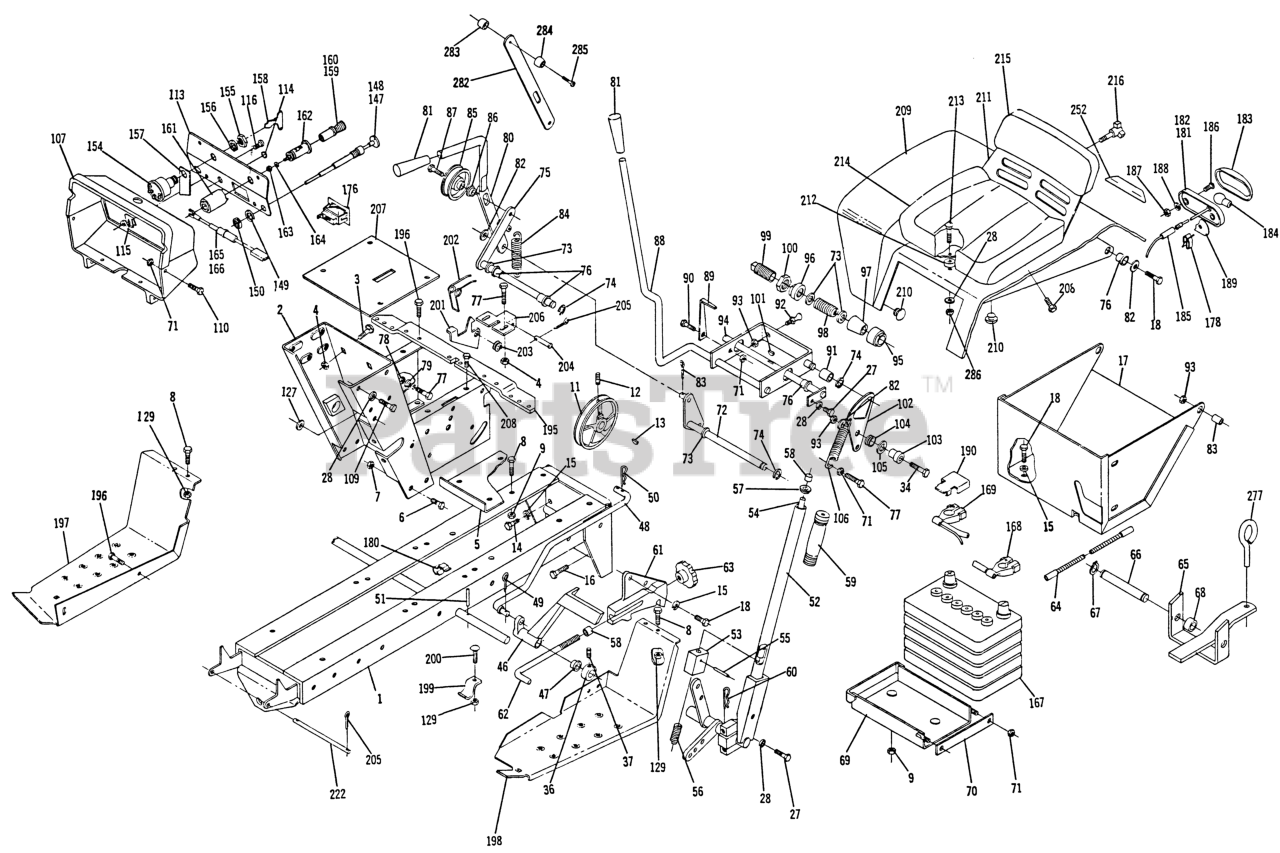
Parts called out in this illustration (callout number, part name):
139	Fuse
140	ASSY FUSED CONN
141	Battery
142	Wiring Harness
143	Wire-Ground
145	Cover Battery Term
146	ASSY REFLECTOR HOUSI
147	WIRE ASSY
148	SPRING
149	BULB
150	Lens
151	Pan HD Swage
152	Switch
153	Harness
154	SPEED CLIP
155	CONNECTOR 3 WIRE
156	CLIP-WIRE
157	Tail Light
158	Base
159	Lens
160	Bulb
161	Mounting Pad
162	CONNECTOR 2 WIRE
163	Screw, 10-32 X 5/8
164	Nut #10-32
165	Lockwasher #10
166	Belt Guard
167	Bolt Hex 7/16-4 x 3/4
168	Lockwasher 3/8
169	Washer 7/16
170	Bracket
171	Bolt, 5/16-18 x 1/2
172	Footrest R.H.
173	Footrest L.H.
174	BRACKET
175	Bolt-Carriage 5/16-18
176	Latch Fender
177	Spring
178	NYLINER BUSHING
179	Pin
180	Hairpin
181	BRACKET FENDER LATCH
182	Bolt-Hex 1/4-20
183	Stop-Fender Latch
184	Cover Plate
185	Bolt, 1/4-20 Whizlock
186	Fender
187	BUSHING-FLANGED
188	Bolt 3/8-24 x 7/8 Hex
189	SPACER
190	GROMMET
191	Seat Base
192	Spacer
193	Bolt-Car. 5/16-18 x 1
194	Nut, 5/16-18
195	Cushion Seat
196	Back Cushion
197	Knob 8 HP
198	Hood
199	Bracket-Grill Pivot RH
200	NYLINER BUSHING
201	Bolt Hex 5/16-18 x 3/4
202	Rod-Pivot
203	Bracket-Grill Pivot LH
204	LEVER HOOD LATCH
205	KNOB
206	SPIROL PIN
207	Roller
208	Nut-Hi Crown
209	SPEED NUT
210	Rod Latch
211	Hood Ornament
212	SPEED NUT
213	ASSY LATCH & SHAF R
214	Hairpin
215	MOUNTING BRACKET R
216	PLATE-MTG BRKT LH R (NS)
217	ASSY BRACKET AND R
218	ROLLER
219	Lock Rod
220	Wheel and Tire
221	Wheel
222	Tire
223	VALVE TUBELESS
224	Lug Nut
225	Wheel-Complete
226	WHEEL
227	Bearing
228	TIRE TURF SAVER 16X6.50-8
229	VALVE TUBELESS
230	WASHER
231	Hub Cap
232	Steering
233	CAP INSERT
234	ROLL PIN 1/4 X 1-1/4
235	Key
236	WASHER-BOWED
237	COLLAR
238	Decal-Hood
240	Decal-Raider 10
241	Decal Shift Pattern
242	Deal-Seat Latch
243	Decal
244	Decal
245	Pin-Tool
246	V BELT
247	PLATE & ROD ASSEM R
248	Bolt, 7/16 14 x 1
249	Nut Conlok 3/8-16
251	ROD ASSY
252	Knob
253	Bracket
254	L/A CLUTCHPLATE&FACI
255	RACE-BEARING
256	RETAINER
257	Clutch Housing
258	Seal
259	SEAL-OIL
260	Bearing
261	Ring-Snap
262	SHAFT
263	DECAL
264	Clutch Plate
265	CLUTCH FACING
266	RIVET-BRASS
